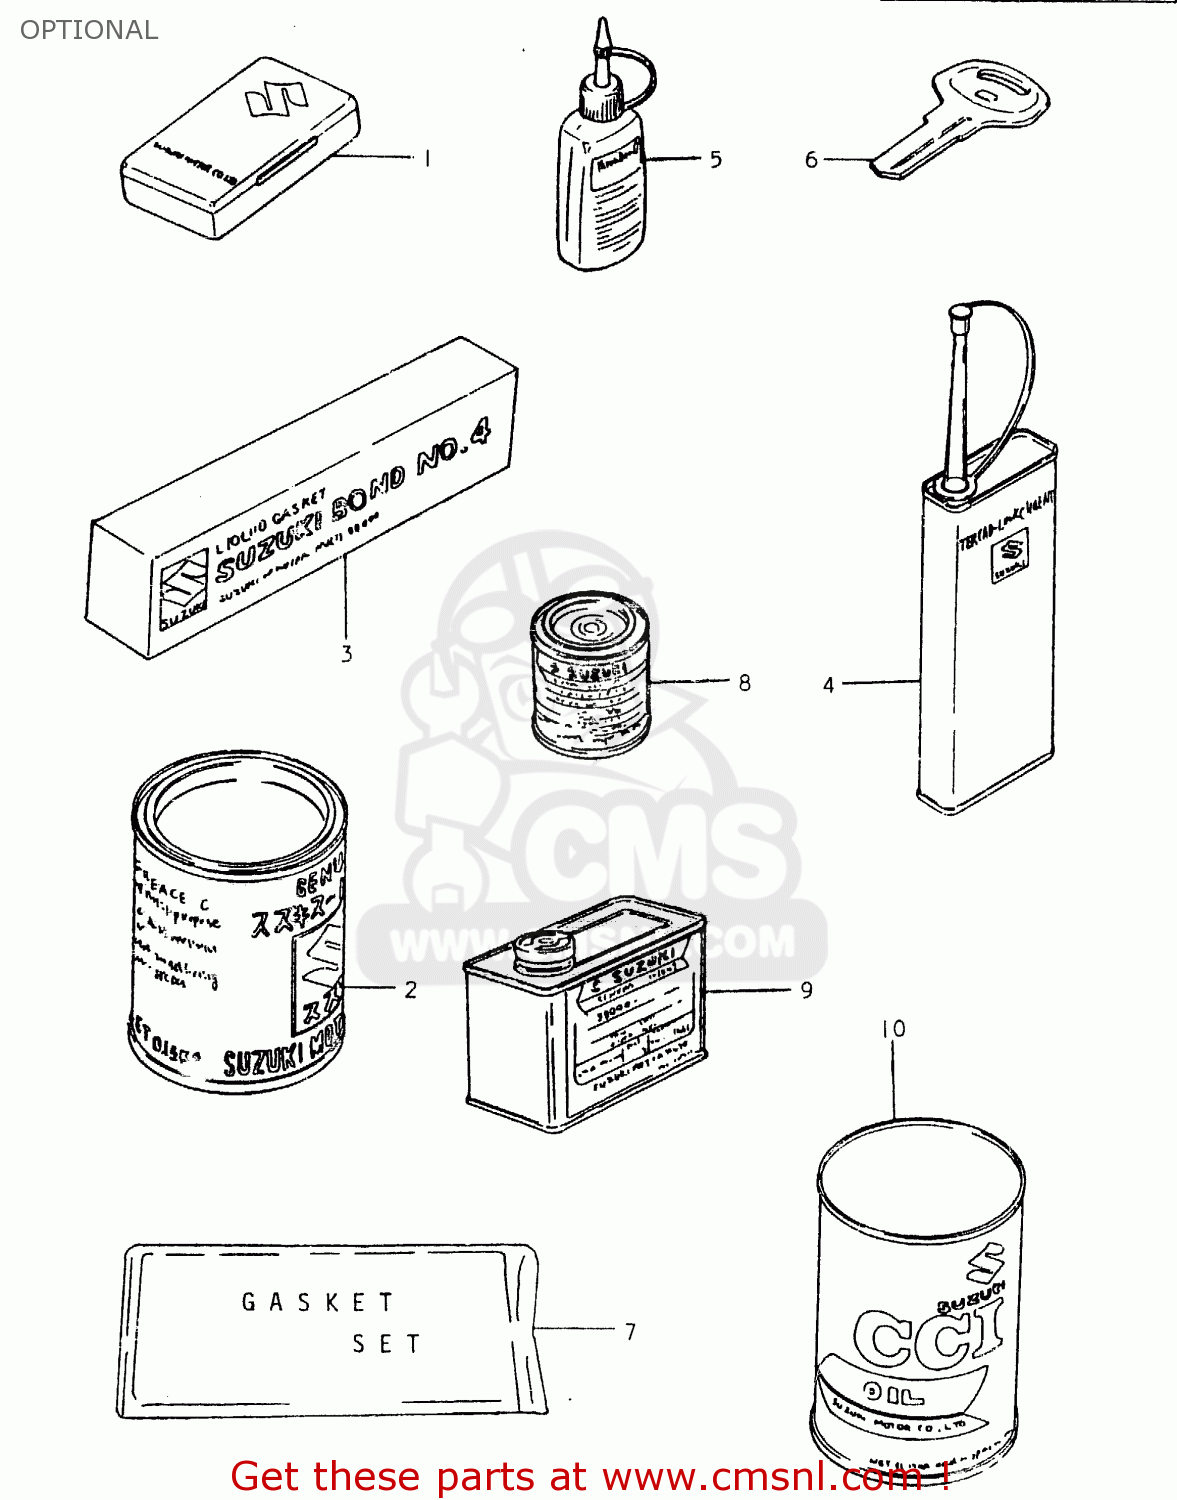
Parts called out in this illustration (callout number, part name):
1	TUBE REPARING TOOL
2	GREASE(C)EP2 LITHIUM 150G
3	BOND 1104
4	THREAD LOCK NO.1401 CLEAR 200G
5	THREAD LOCK NO.1303B PURPL 50G
6	KEY,BLANK
7	GASKET SET (MCA)
8	PAINT,BLACK
9	PAINT (BLACK)
10	CCI OIL
